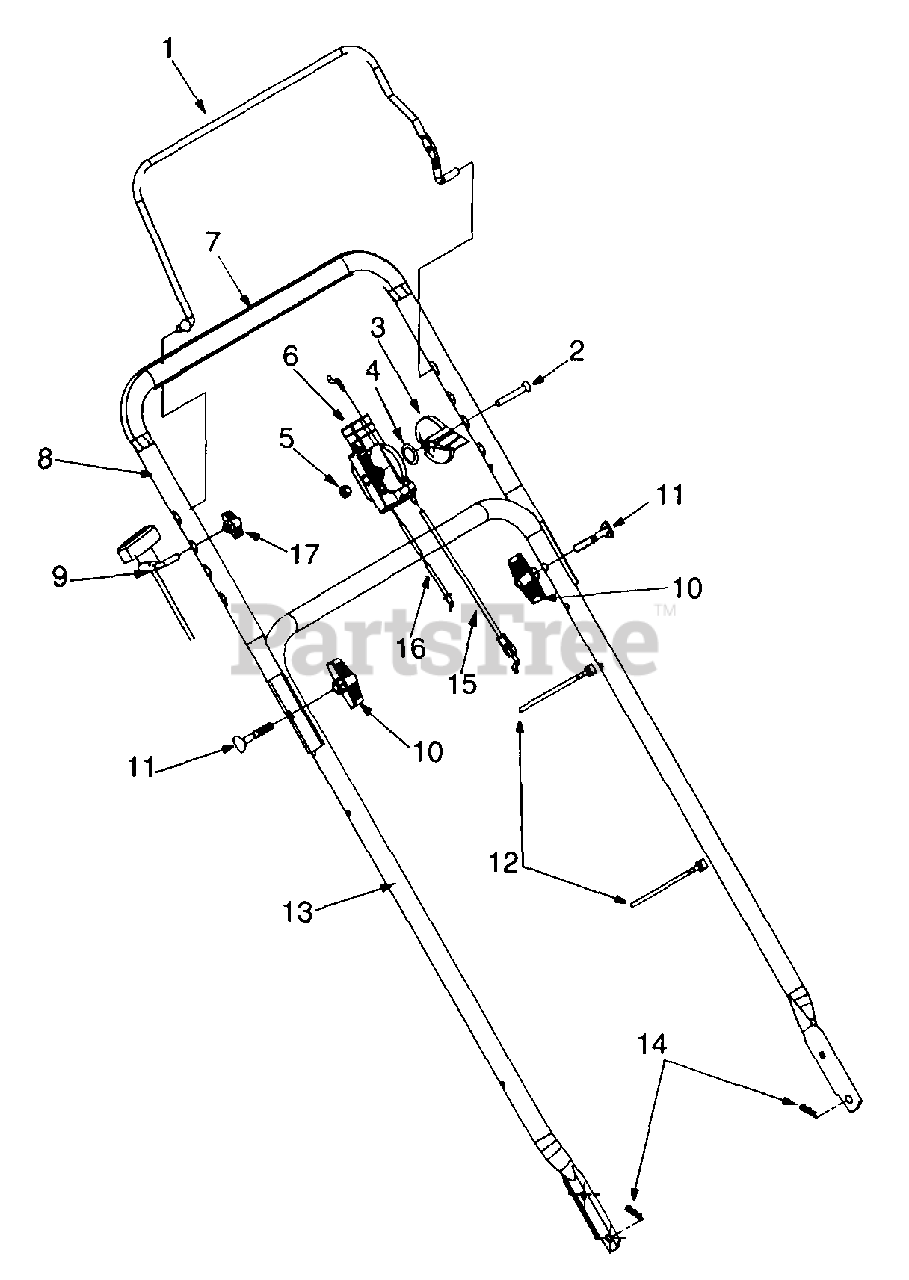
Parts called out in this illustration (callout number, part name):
2	Oval C-Sunk Screw
3	Throttle Lever
4	Curved Spring Washer
5	Hex Lock Nut
6	Throttle Housing w/ERS
7	Foam Grip
10	Hand Knob
11	Carriage Bolt
12	Cable Tie
13	Lower Handle
14	Hairpin Clip
15	Control Cable 39"
16	Throttle Cable 42"
17	Handle Knob
